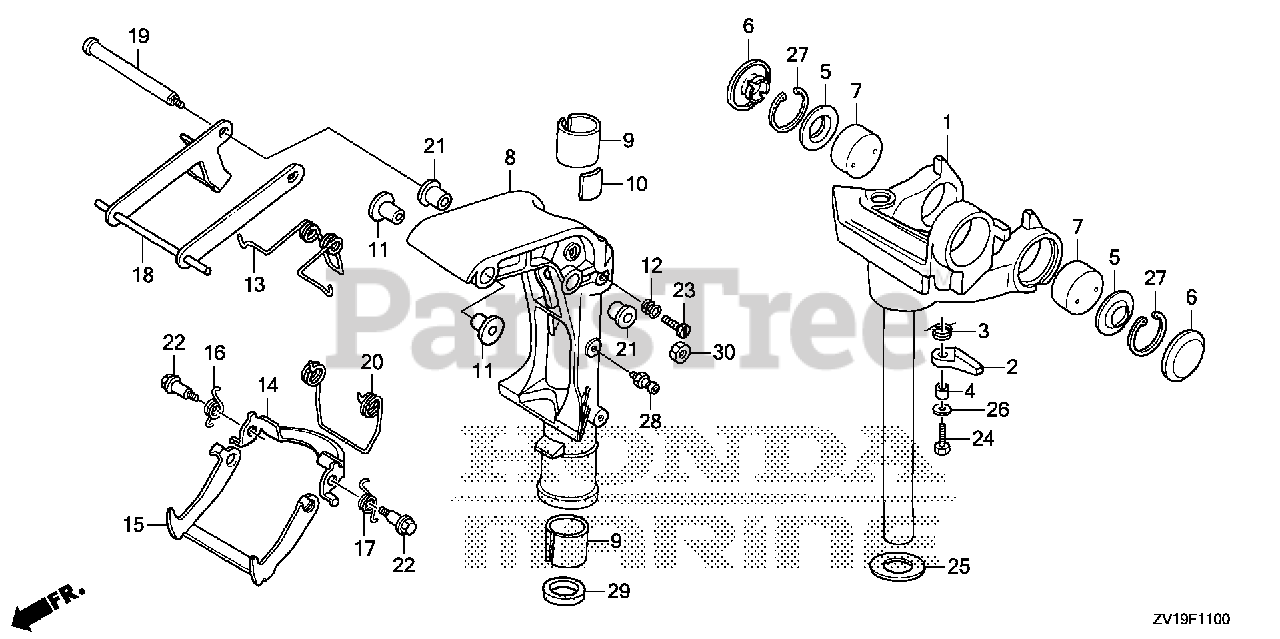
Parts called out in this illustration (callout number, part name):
1	FRAME, MOUNTING *NHB14M* (AQUA MARINE SILVER METALLIC)
2	STOPPER, HANDLEBAR *NHB14M* (AQUA MARINE SILVER METALLIC)
3	SPRING, HANDLE
4	COLLAR, STOPPER
5	WASHER, MOUNTING
6	CAP, MOUNTING
7	RUBBER, MOUNTING (UPPER)
8	CASE, SWIVEL *NHB14M* (AQUA MARINE SILVER METALLIC)
9	LINER, SWIVEL CASE
10	BLOCK, FRICTION
11	BUSH, SWIVEL CASE
12	SPRING, FRICTION ADJUSTING
13	SPRING, HOOK RETURN
14	PLATE, REVERSE LOCK
15	HOOK, REVERSE LOCK
16	SPRING, R. REVERSE LOCK
17	SPRING, L. REVERSE LOCK
18	ARM, TILT
19	SHAFT, TILT
20	SPRING, REVERSE LOCK
21	BUSH, TILT LEVER
22	BOLT, REVERSE LOCK
23	BOLT, SPECIAL (8X20)
24	BOLT, HEX. (6X20)
25	WASHER, THRUST
26	WASHER, PLAIN (6MM) Use up to Frame SN 4800342.
27	CIRCLIP (INNER) (40MM)
28	NIPPLE, GREASE
29	OIL SEAL (27.8X33X5) (ARAI)
30	NUT, HEX. (6MM)
